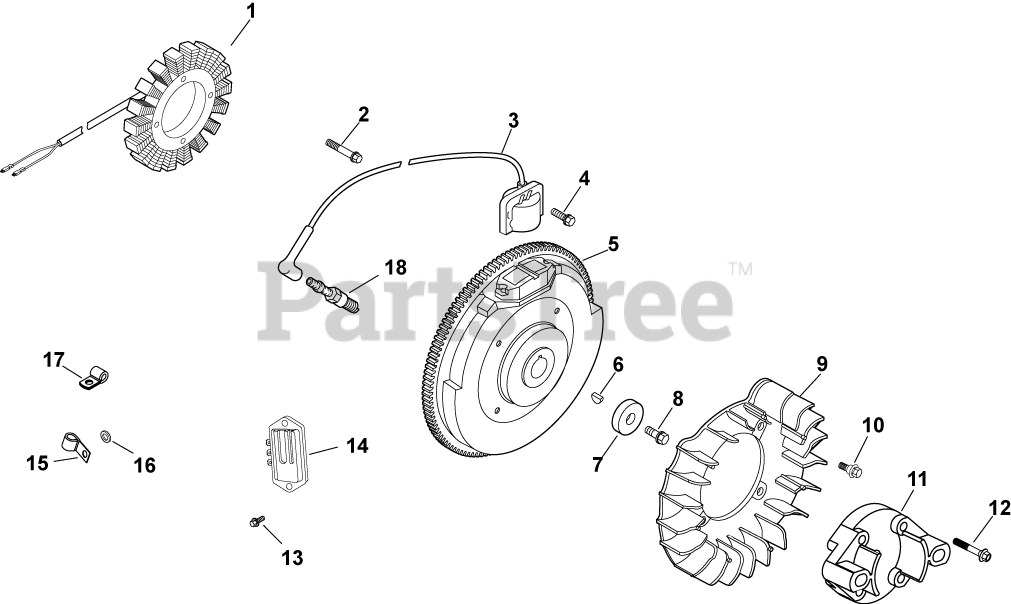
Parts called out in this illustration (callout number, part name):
1	KIT, 15 / 20 AMP STATOR
2	SCREW, M5X0.8X25 - (#25086402S)
3	MODULE, EMC/RFI COMPLIANT
4	SCREW, FLG THD FRM M5X.8X20-(#25086399S)
5	FLYWHEEL, PAINTED-USE 24 025 59-S
6	KEY, 3/16" X 5/8"
7	WASHER, FLAT 13/32"
8	SCREW, FLG M10X1.5X45 - (#25086361S)
9	FAN USE 24 755 253-S
10	BOLT, SHOULDER
11	ADAPTER, DRIVE SHAFT
12	SCREW, FLG M8X1.25X45
13	SCREW, HEX FLANGE HI-LO
14	REG/RECT-15 AMP (KM)-USE 41 403 10-S
15	CLIP, CABLE
16	WASHER, FLAT 1/4" (O.D. 1/2")
17	CLIP, TUBE & WIRING (KM)
18	SPARK PLUG, RFI
